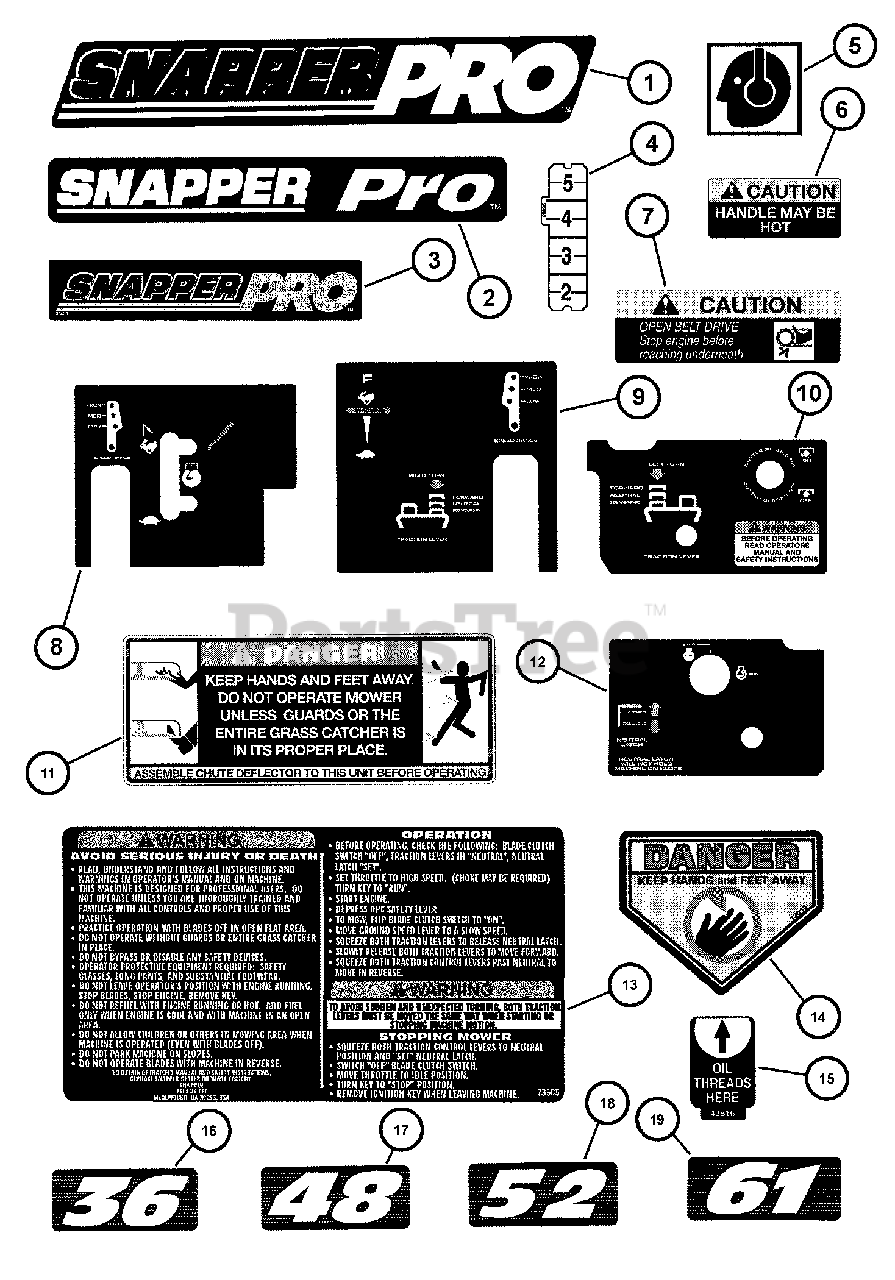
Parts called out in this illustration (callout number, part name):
1	DECAL, Snapper Pro (silver, 16-1/2" long)
2	DECAL, Snapper Pro w/Trademark (white letters, 13-3/16" long)
3	DECAL, Small Snapper Pro (silver, 8" long)
4	DECAL, Height of Cut
5	DECAL, Ear Protection
6	DECAL, Adjustment Handle
7	DECAL, Caution, Open Belt Drive
8	DECAL, Left Panel, Throttle w/Choke (Hydro)
9	DECAL, Right Panel, Instructions
10	DECAL, Left Panel, Switch
11	DECAL, Danger Guard/Catcher
12	DECAL, Right Panel, Switch
13	DECAL, Caution Pro Hydro
14	DECAL, Danger (CPSC) Cut Finger
15	DECAL, Oil Threads Here (Adjustable Decks only)
16	DECAL, 36" Deck Commercial
17	DECAL, 48" Deck Commercial
18	DECAL, 52" Deck Commercial
19	DECAL, 61" Deck Commercial
